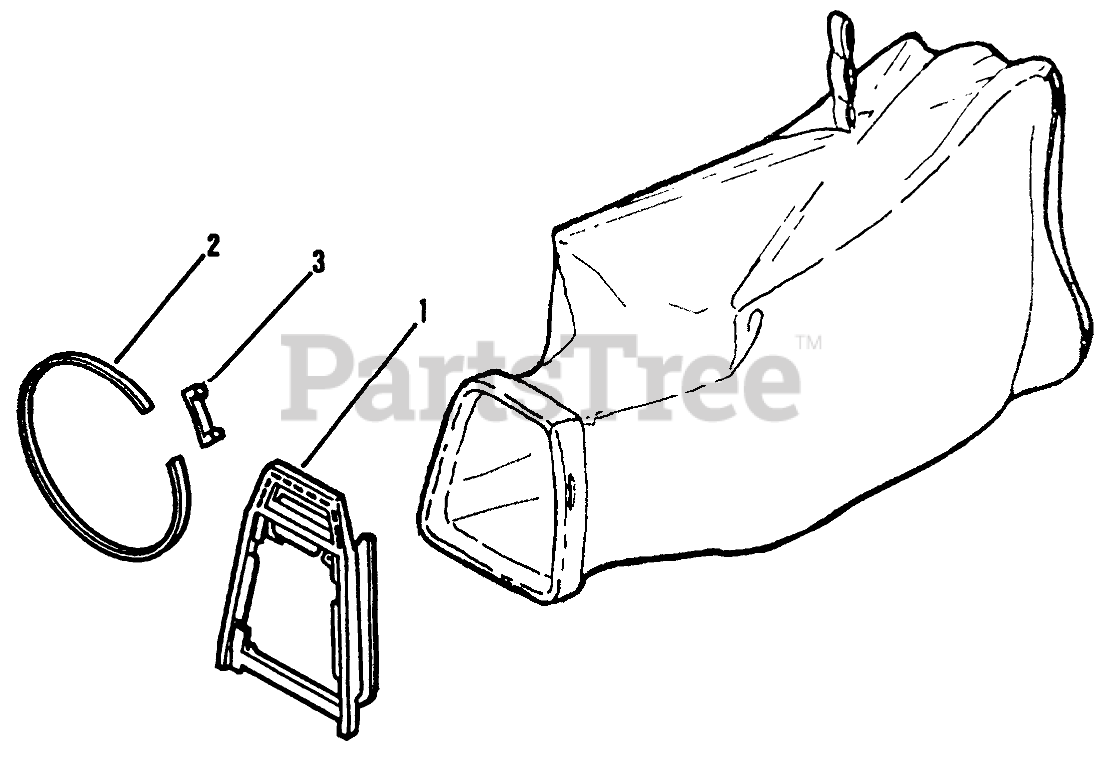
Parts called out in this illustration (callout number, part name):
1	CHUTE - ADAPTER
2	Strap
3	LOCK STRAP IAC
